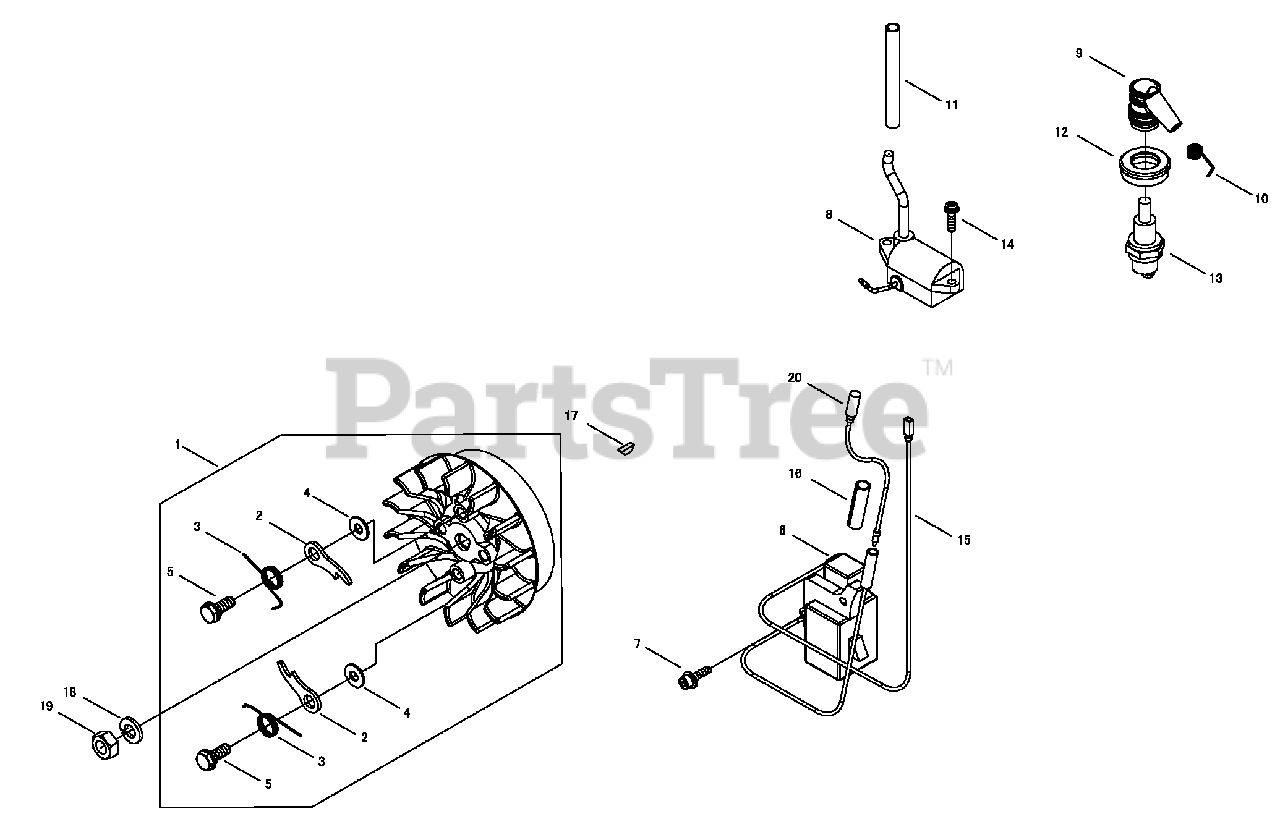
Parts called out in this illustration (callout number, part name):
1	FLYWHEEL
2	PAWL, STARTER
3	SPRING, RETURN
4	WASHER - 6
5	BOLT
6	COIL, IGNITION
7	SCREW - 4X20
8	COIL, IGNITION
9	CAP, SPARK PLUG
10	TERMINAL, SPARK PLUG CAP
11	TUBE
12	COVER, DUST
13	SPARK PLUG -- BPMR-7A
14	SCREW - 4X16
15	CORD
16	TUBE
17	KEY - 3X10
18	LOCKWASHER - 8
19	NUT
20	CORD
